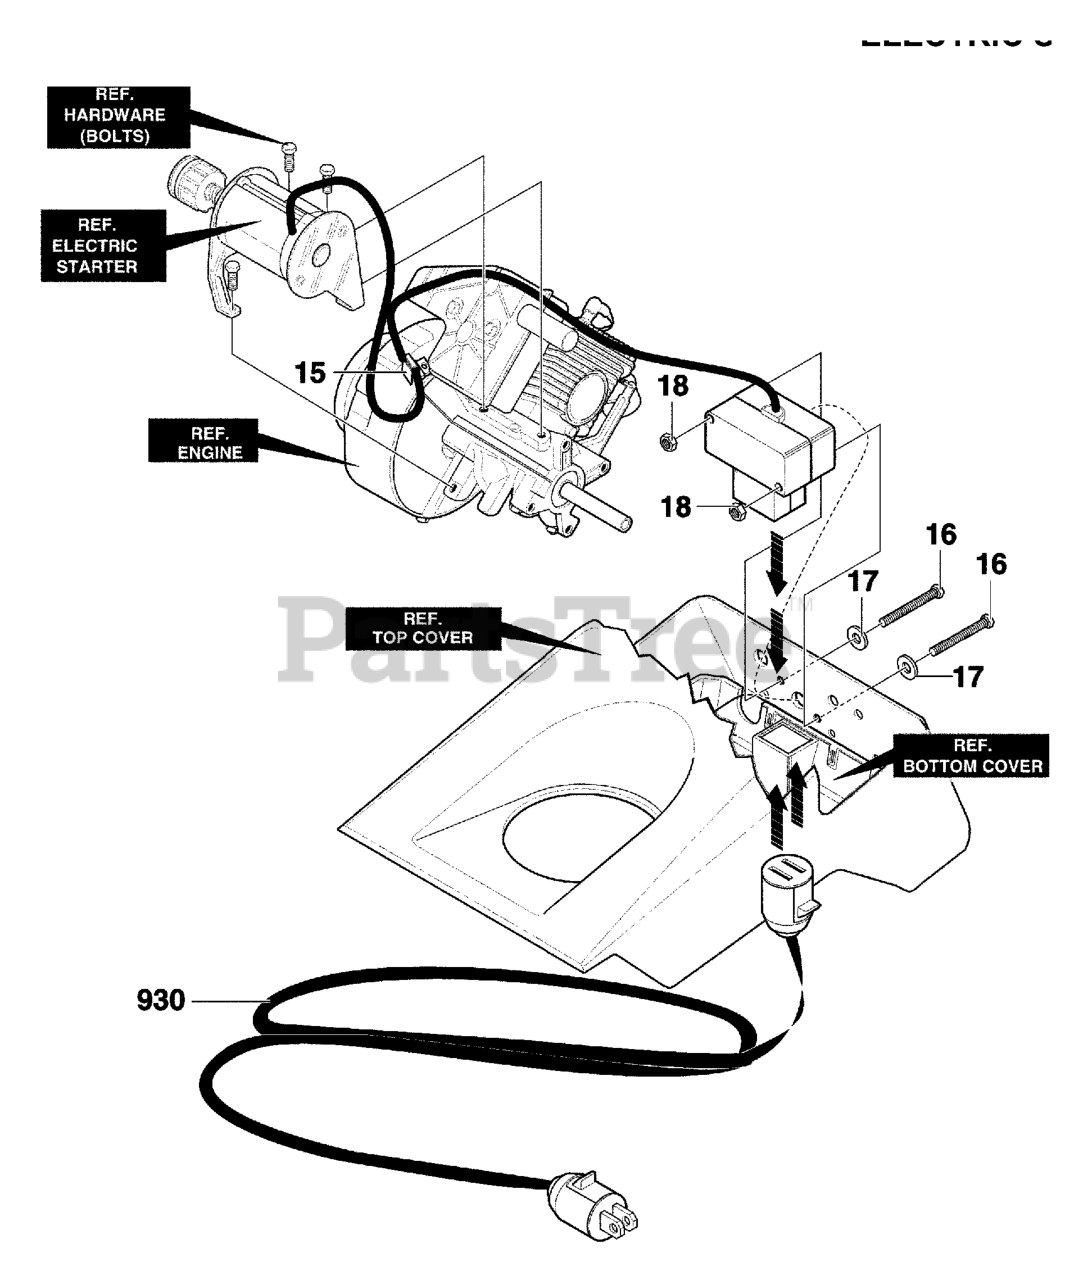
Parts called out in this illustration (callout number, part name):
15	RETAINER
16	SCREW #8-32X3.00
17	WASHER, FLAT .188X.38X.040
18	NUT, #8-32X3.00
930	CORD EXTENSION
